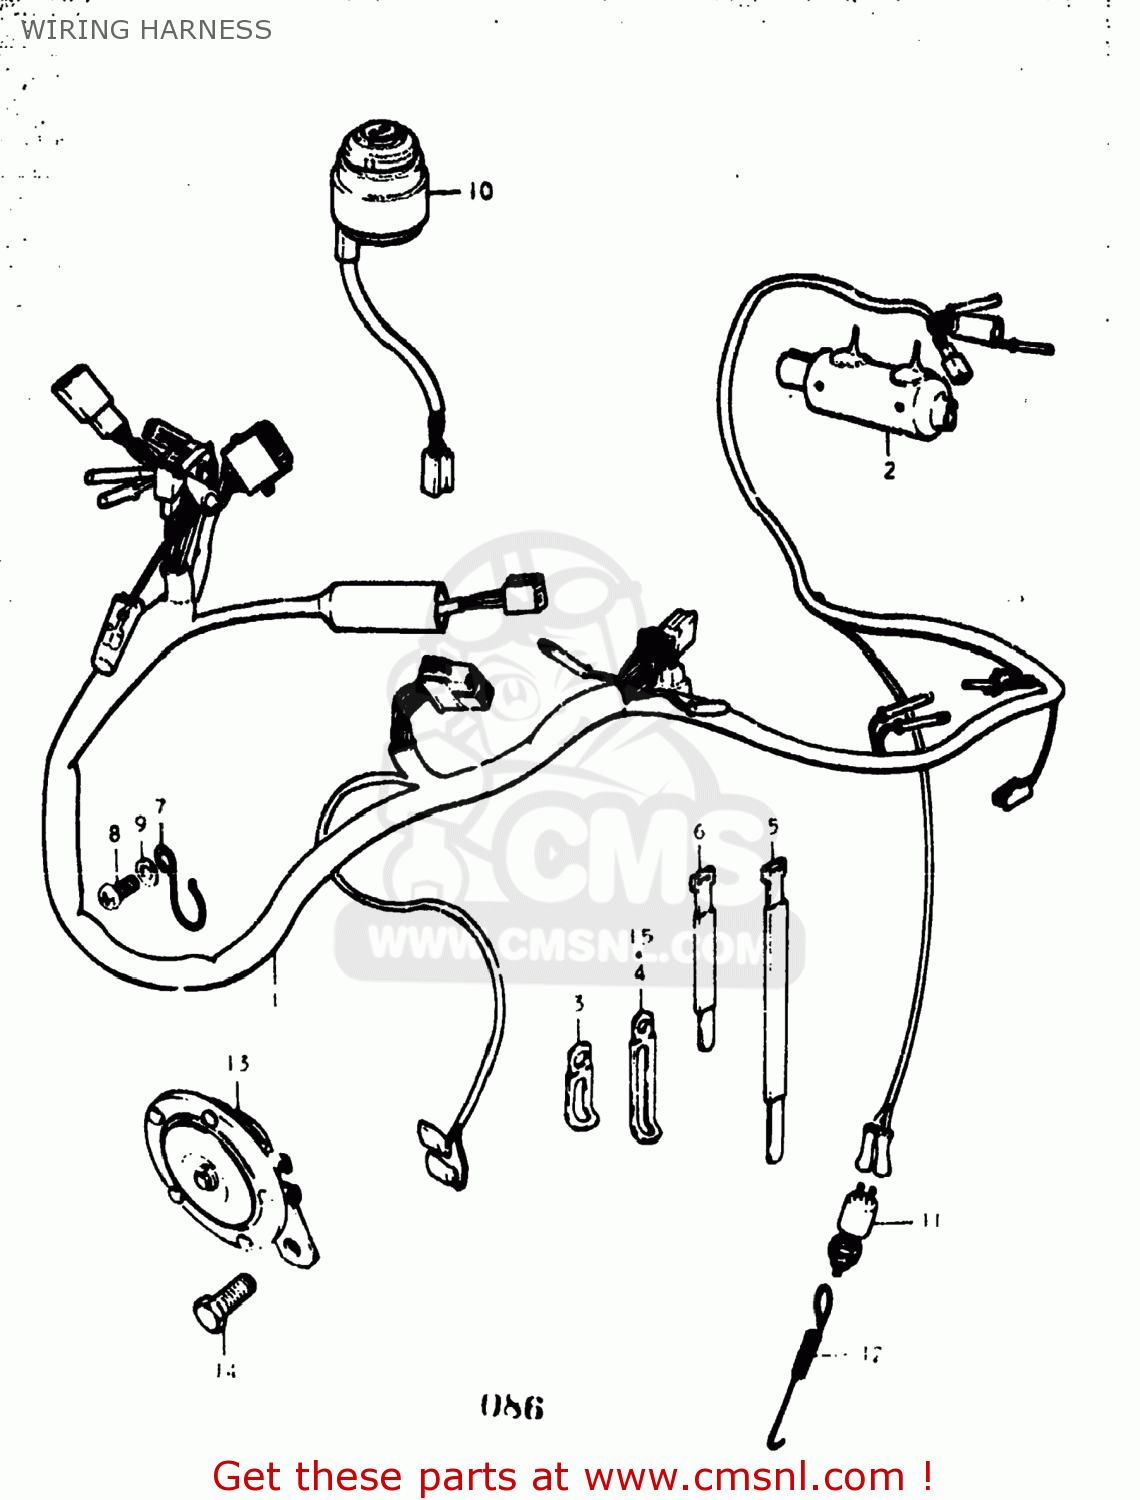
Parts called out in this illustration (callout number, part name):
1	HARNESS,WIRING
2	BOOT,WIRING HARNESS
3	CLAMP
4	CLAMP
5	CLAMP
6	CLAMP
7	GUIDE,WIRING HARNESS
8	SCREW 6X12
9	WASHER 6MM
10	SWITCH ASSEMBLY,IGNITION
11	SWITCH ASSY,BRAKE LAMP
12	SPRING
13	HORN ASSY
14	BOLT
15	CLAMP
